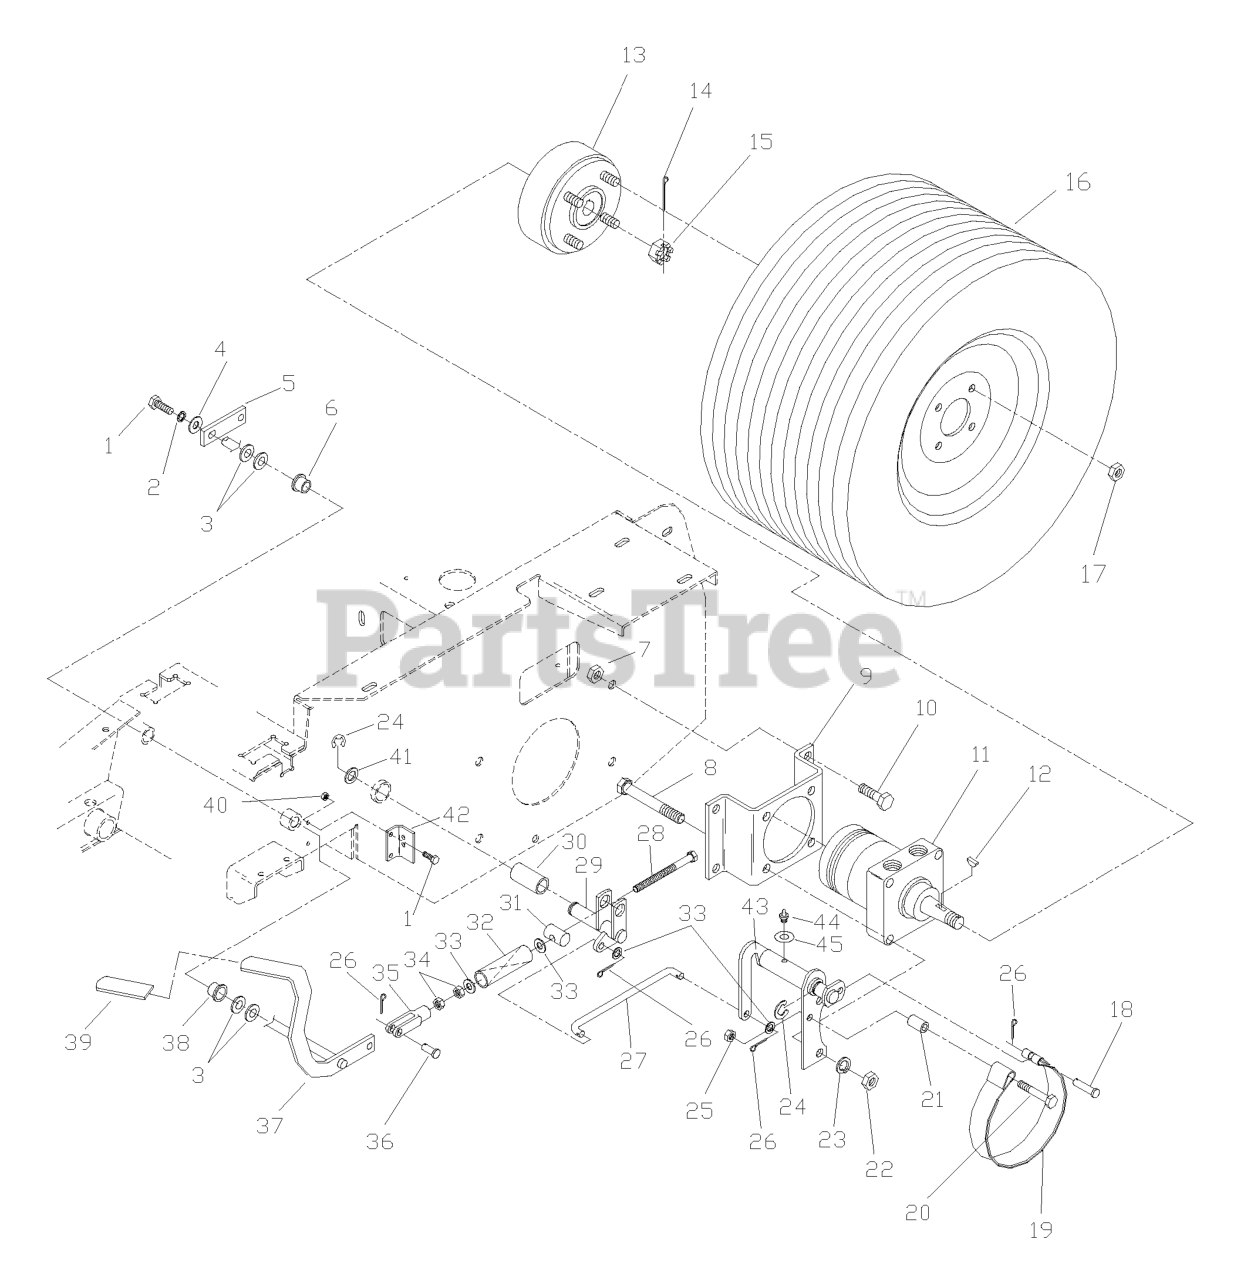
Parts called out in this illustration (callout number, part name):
1	HCS 1/4C X 3/4 HCS
2	LOCKWASHER 1/4"
3	WASHER, 7/16 DISC SPRING
4	WASHER 1/4 FLAT
5	ARM, PARK BRAKE
7	NUT 1/2-13 HEX NYLOC ZD
8	HCS 1/2C X 2 3/4
9	MOTOR STANDOFF - PAINTED
10	HCS 1/2C X 1 1/4 SERRATED HEAD
11	MB WHEEL MOTOR
12	WOODRUFF KEY
13	HUB W/BRAKE DRUM
14	COTTER PIN
15	CASTLE-NUT
16	TIRE.24X12-12.TURF.MASTER
16	RIM (REAR)
16	VALVE STEM TR-412
17	LUG NUT 1/2F
18	CLEVIS PIN, 3/8 X 1 1/2
19	BRAKE BAND
20	HCS 3/8 X 3 GD.8
22	NUT HEX 1/2
23	WASHER 1/2" SPLIT LOCK
24	E RING 3/4
25	NUT 3/8C CENTERBLOCK
26	RP_COTTER PIN 1/8 X 3/4
27	BRAKE LINKAGE, LT.
27	BRAKE LINKAGE, RT.
28	HCS 3/8F X SPECIAL
30	BRONZE BEARING
31	TRUNION PIN
33	WASHER 3/8 SAE FLAT
35	YOKE-3/8-24 PLTD
36	CLEVIS PIN 3/8 X 1 1/8
37	BRAKE LEVER WIDMT
39	GRIP, PARK BRAKE
40	NUT 1/4C CENTERLOCK
43	LT.BRAKE WLDMT
43	RT.BRAKE WLDMT
44	ZERK
